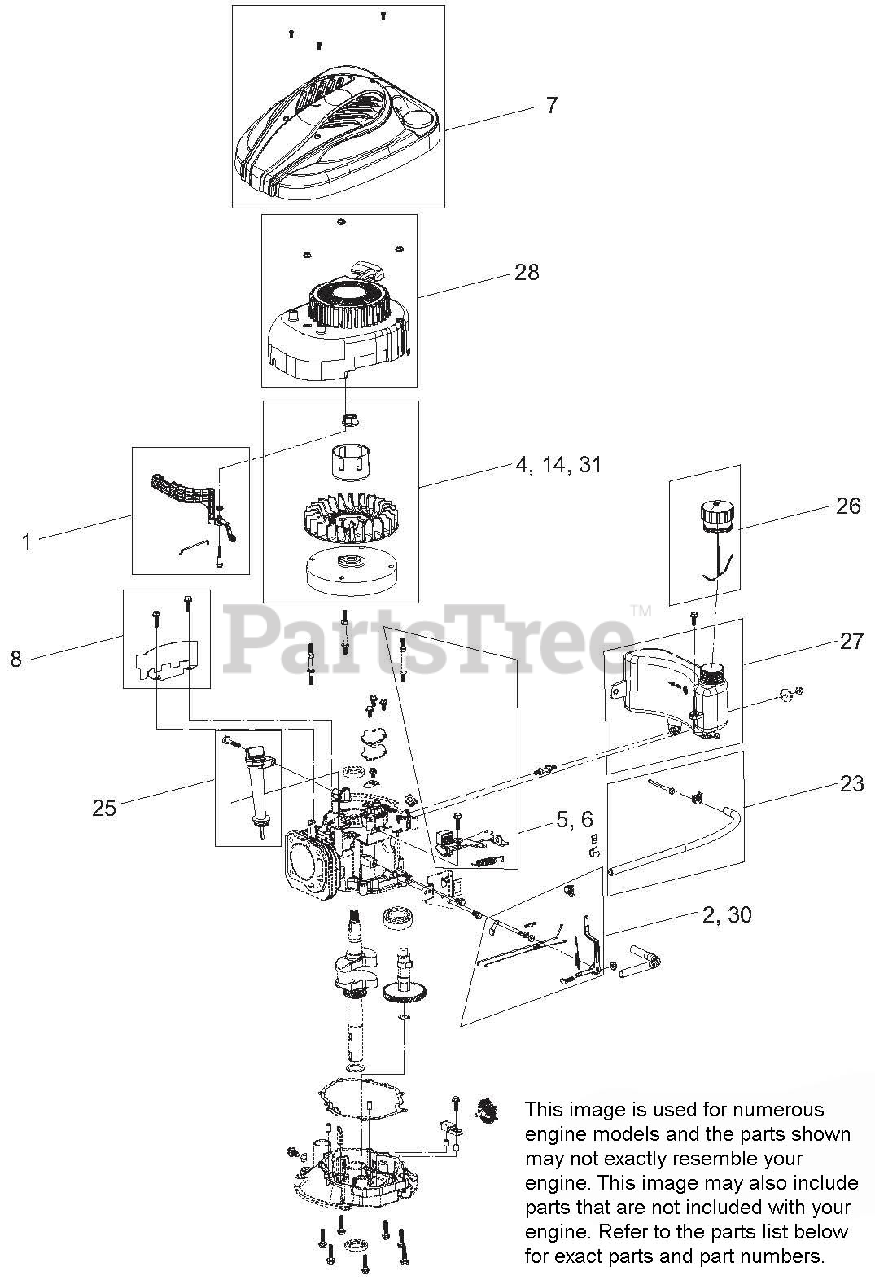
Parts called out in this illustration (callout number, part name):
1	KIT, AIR VANE CHOKE - SVC
7	KIT, ARIENS STYLE - SVC
8	KIT, FLYWHEEL SHIELD - SVC
23	KIT, FUEL LINE W/FILTER - SVC
25	DIPSTICK, OIL - SVC
26	TUBE, OIL DIPSTICK - SVC
27	ASM, FUEL TANK W/HARDWARE
28	KIT, RECOIL - SVC
30	KIT, GOVERNOR ARM (BBC)
30	KILL SWITCH, ENGINE, BBC
31	KIT, FLYWHEEL AND FAN (BBC)
